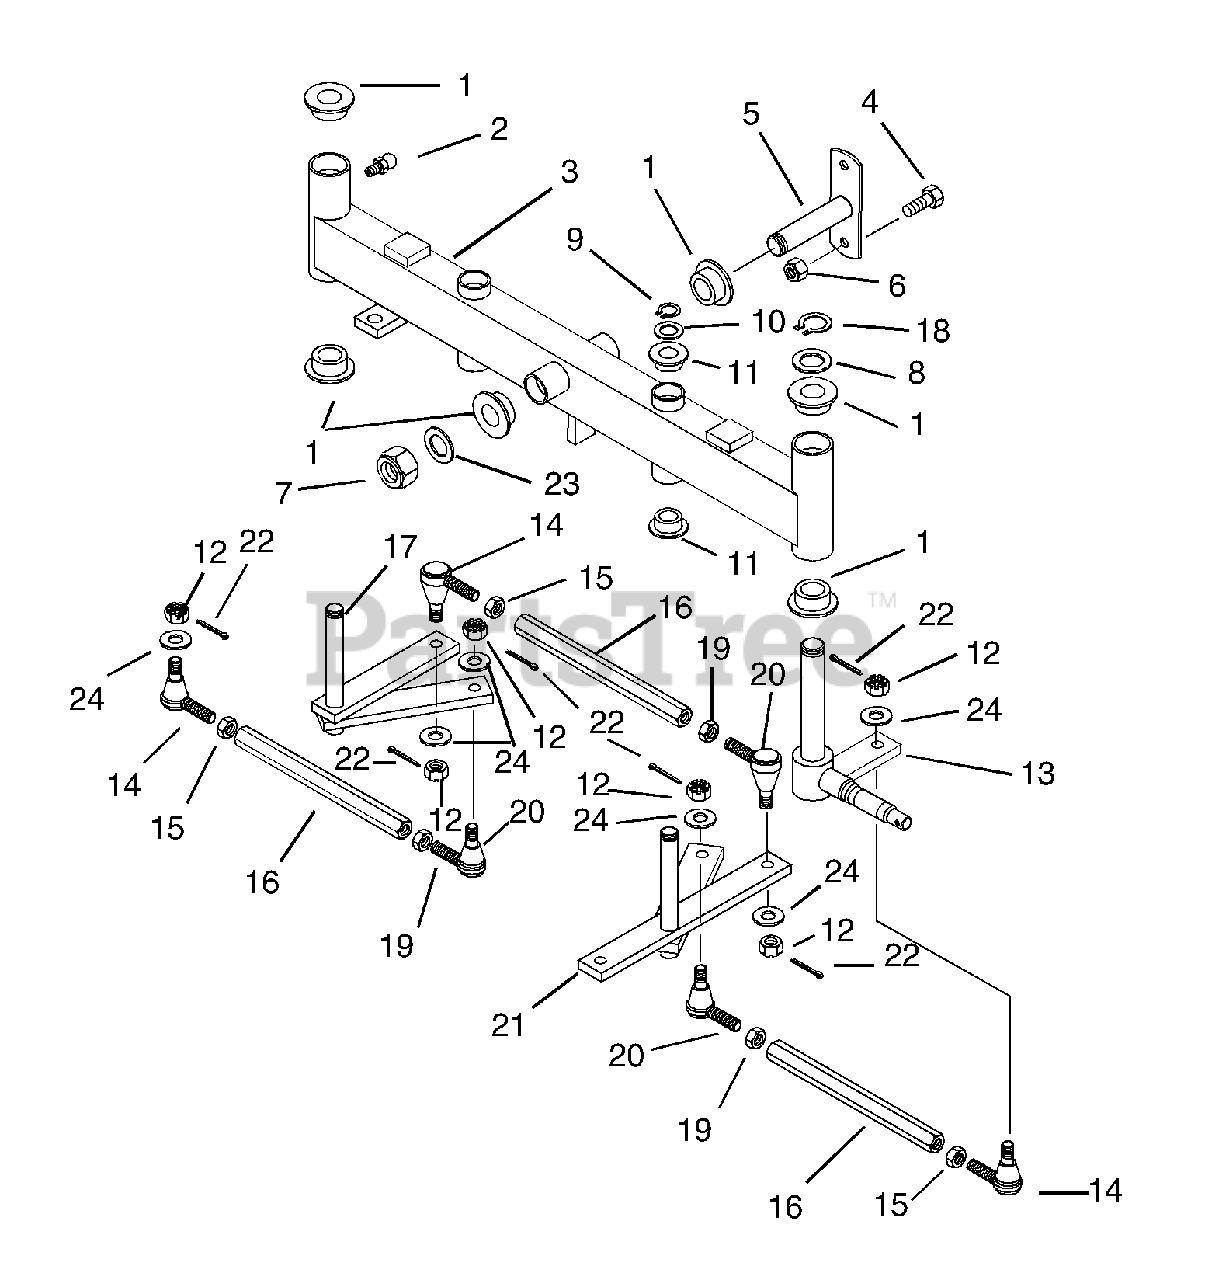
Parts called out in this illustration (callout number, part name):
1	Bushing-Flange 1.020 x 1.385 x .75 x 1.75
2	Fitting-Lube .25-28 x .256
3	Weldment, Axle
4	Bolt-Hex .38-16 x 1.00 Grade 5
5	Weldment, Axle Pin
6	Nut-Locking-Center .38-16
7	Nut-Locking 1.0-14
8	Washer-Hardened Thrust 1.00 X 1.55 X .03
9	Ring-Retaining-External .689 x .077
10	Bearing-Needle-Thrust .752 x 1.24 x .031
11	Bushing-Flange .762 x 1.0 x .580 x 1.48
12	Nut-Castle .38-24
13	Weldment, Kingpin Left Hand
13	Weldment, Kingpin Right Hand
14	Ball Socket - Right Hand
15	Nut-Jam .50-20 Grade 2
16	Rod, Tie
17	Weldment, Steering Idler
18	Ring, Retaining External .906 x .078
19	Nut-Jam .50-20 Left Hand Grade 2
20	Ball Socket - Left Hand
21	Weldment, Steering Arm
22	Pin, Cotter .09 x .75
23	Washer-Flat-Steel 1.062 x 2.0 x .134
24	Washer-Flat-Steel .406 x .812 x .065
